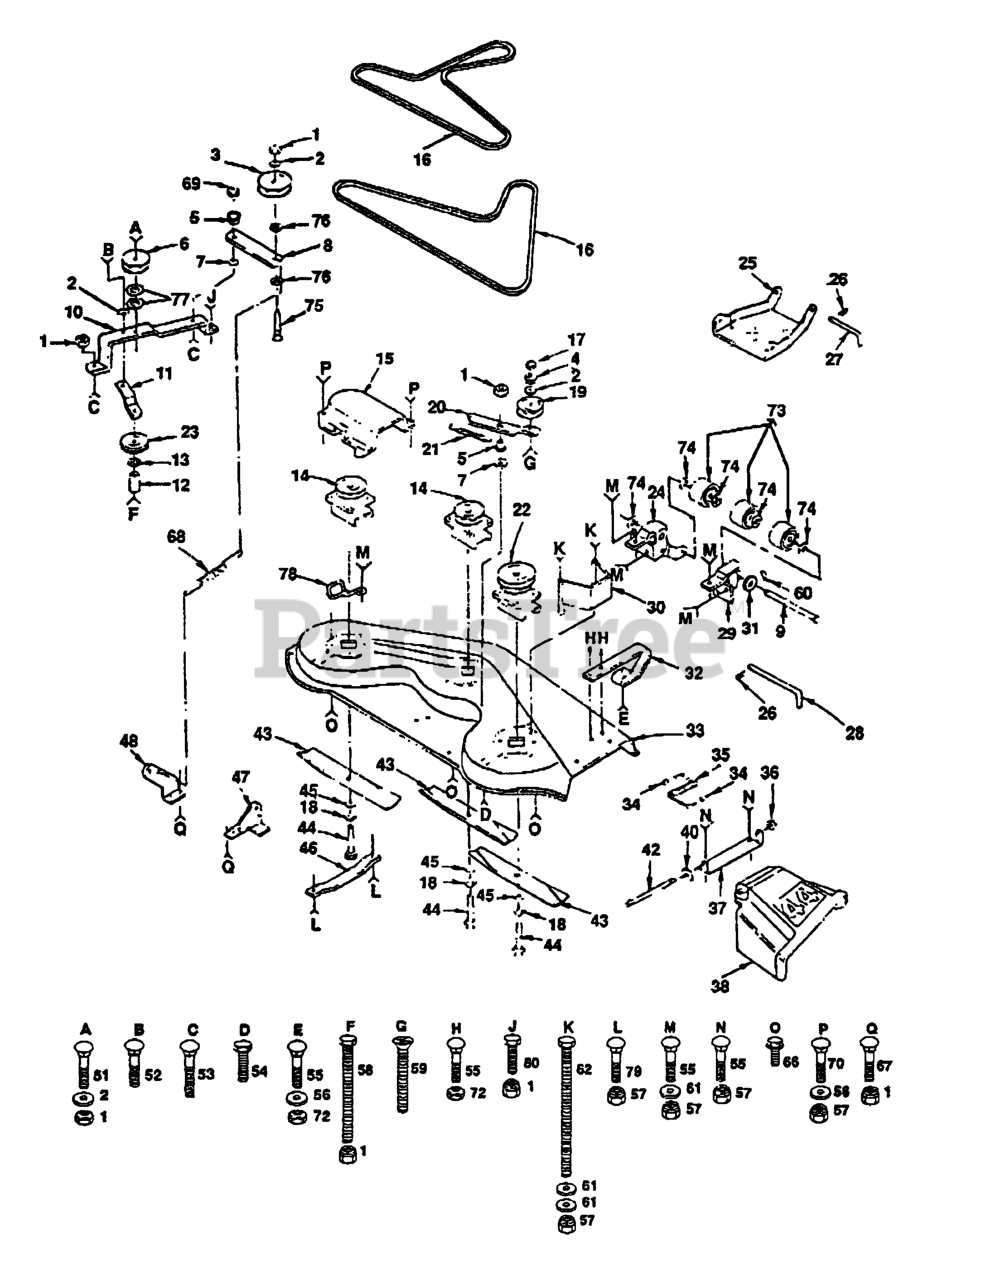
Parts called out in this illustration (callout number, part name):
2	WASHER
3	PULLEY.IDLER.FLAT.MOWER.BLK.PT
4	WASHER, LOCK 3/8
5	SPACER RETAINER
6	IDLER-INSIDE T
7	WASHER, WEAR LT (1 2)
9	PIVOT PIN T
10	BAR-SUPPORT YT
11	BRACE-IDLER YT
13	WASHER
14	JACKSHAFT YT
17	NUT.HEX.3/8-16UNC
18	LOCKWASHER
19	IDLER.FLAT.GTV
20	ARM-IDLER YT
21	SPRING T
22	JACKSHAFT YT
23	IDLER-FLAT T
24	BRACKET LH YTH
25	LINK,PARALLEL
26	SPRING TI
27	ROD,FRT PARALL LT
28	HINGE PIN T
29	BRACKET RH YTH
30	GUARD BELT HYT
31	WASHER
32	RUNNER-RH YTV
33	HOUSING
34	CAP-SLEEVE LT
35	DEFLECTOR SPRG T
36	NUT PUSH M
37	BRACKET T
38	DEFLECTOR SHIELD
40	Washer 11/32 x 5/8 x 16 Gauge
42	ROD-HINGE T
43	BLADE
44	BOLT.3/8-24X1-1/2
45	WASHER
46	RUNNER-LH M
47	BRKT SUSP REAR RH
48	BRKT SUSP REAR LH
51	BOLT
52	BOLT D
53	Soft, Carriage 3/8-16 x 1-1/2
55	RP BOLT 5/16-18 X3/4 ZN/YEL GR
56	WASHER
57	LOCKNUT
58	BOLT
60	COTTER PIN
61	WASHER M
62	Bolt, Hex 5/16-18 x 5
66	SCREW
67	Bolt, Carriage 3/8-16 x 3/4
68	SPRING.EXT.8.5"
69	LOCKNUT
70	BOLT.CARR.SQNK.5/16-18UNC.X3/4
74	WASHER T
75	BOLT
76	WASHER
77	WASHER
78	BELT RETIANER
79	BOLT.CARR.5/16-18X5/8.SHORT
80	BOLT
